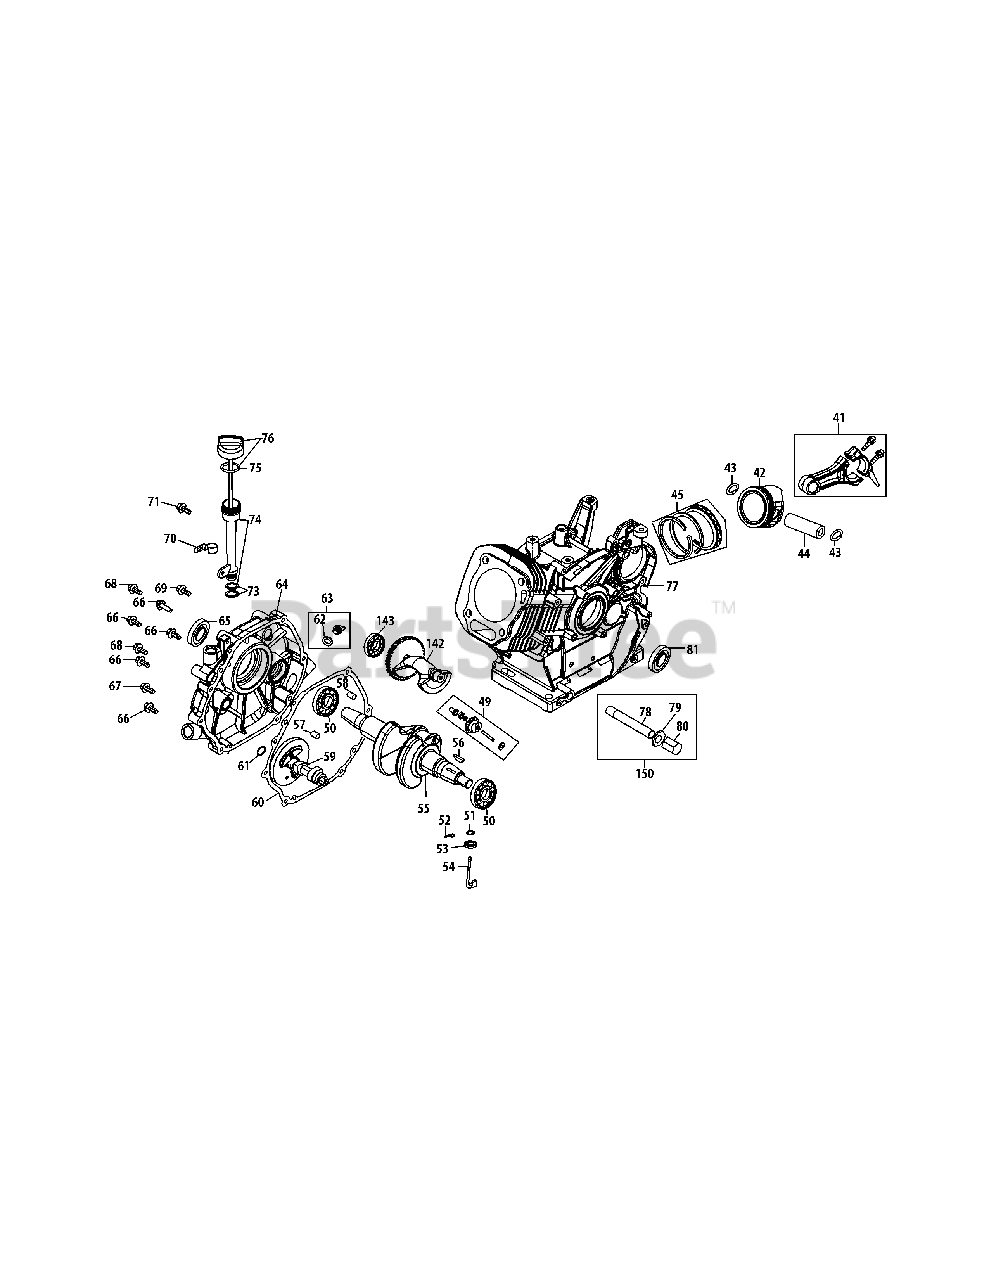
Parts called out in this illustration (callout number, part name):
41	Connecting Rod Assembly
43	Piston Pin Snap Ring
44	Piston Pin
45	Piston Ring Set
49	Governor Gear/Shaft Assembly
50	Radial Ball Bearing 6202-P6
51	Washer 8×20×0.8
52	Cotter Pin
53	Governor Seal
54	Governor Arm Shaft
55	Crankshaft Kit
56	Woodruff Key
57	Dowel Pin 9×12
58	Dowel Pin 7×14
59	Camshaft Assy.
60	Crankcase Cover Gasket
61	Washer 16×24×0.5
62	O-Ring 16×3
63	Oil Filler Plug Assembly
64	Crankcase Cover Kit
65	Oil Seal 30×46×8
66	Bolt M8×38
67	Bolt M8×45
68	Bolt M8×35
69	Bolt M6×16
70	Dipstick Clamp
71	Bolt M6×8
73	Oil Fill Tube O-Ring
74	Oil Fill Tube Assembly
75	Dipstick O-Ring
76	Dipstick Assembly
77	Crankcase Kit
78	Oil Drain Pipe Assy.
79	Washer 10×16×1.5
80	Oil Drain Plug
81	Oil Seal 35×52×7
142	Balanceable Shaft Assy.
143	Bearing 6207-P6
150	Oil Drain Assembly
